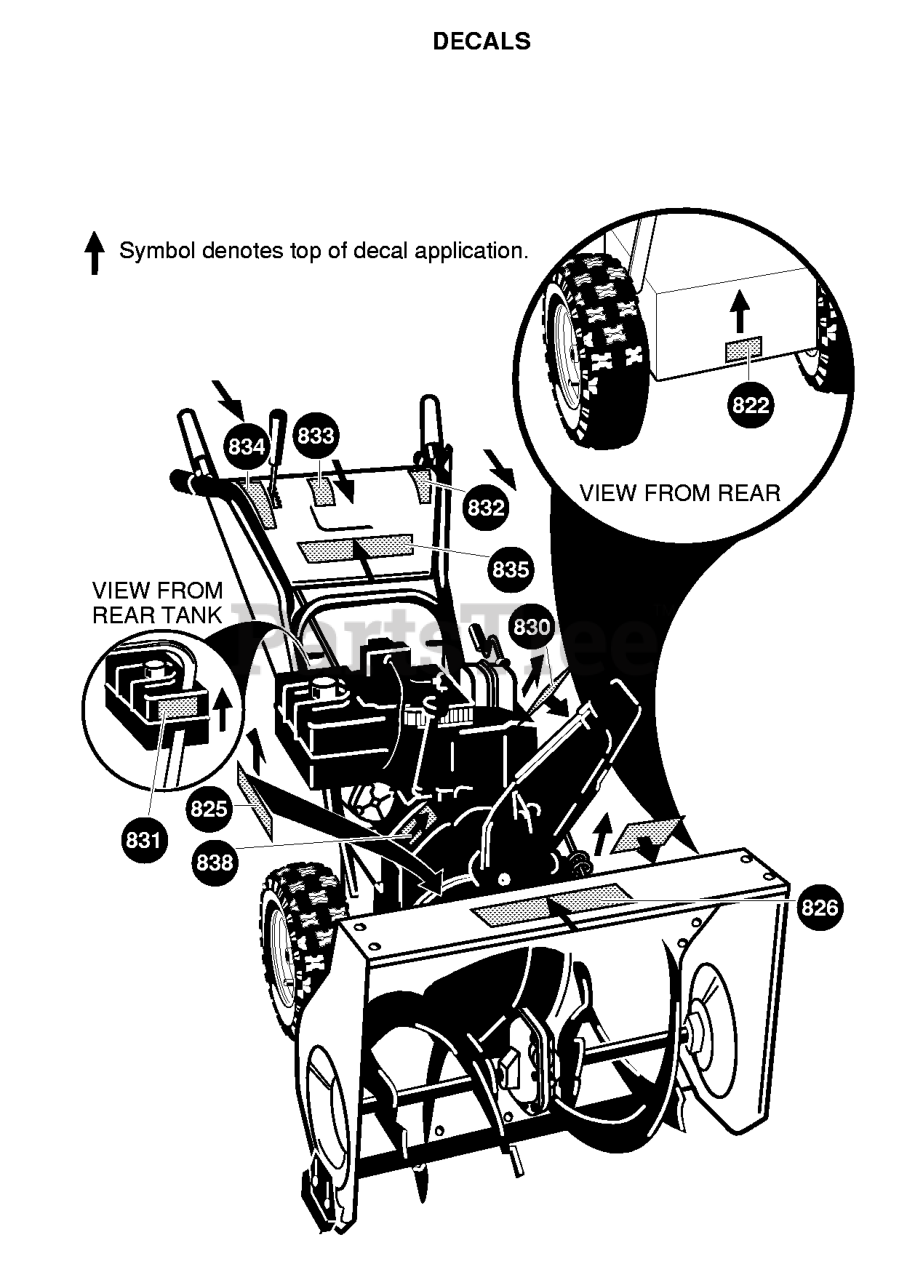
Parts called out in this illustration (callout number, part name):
822	DECAL, DISC ADJUSTMENT
824	DECAL, DANGER FOOT
826	DECAL, HUSQ ST927E
830	DECAL, DANGER FINGER
832	DECAL, TRACTION DRIVE
833	DECAL, SNOW CONDITIONS
834	DECAL, GEAR SELECTOR
835	DECAL, CONTROL PANEL
838	DECAL, BELT ADJUSTMENT
